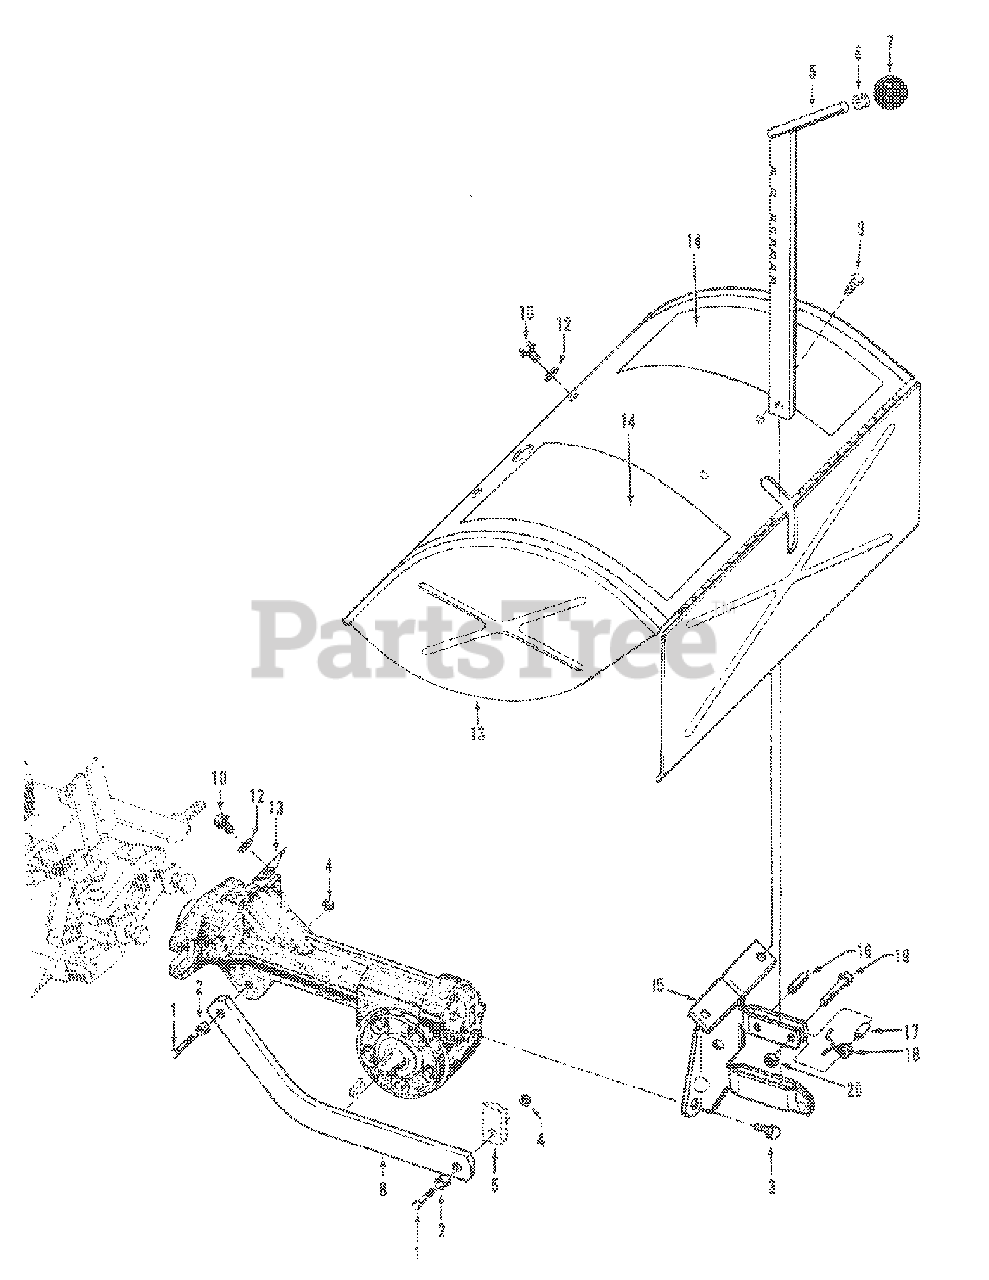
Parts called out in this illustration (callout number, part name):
1	Bolt-hex hd., 3/8-16 x 1-1/4"
2	Bushing-19/64" (.300" lg)
3	Bolt-flanged hex, 5/16-18 x 5/8"
4	Nut-hex, 3/8"-16
5	Bar-depth regulator
6	Ring-retaining
7	Knob-depth regulator
8	Bar-drag, depth
9	Screw-thread-forming, 1/4-20 x 1/2"
10	Bolt-flanged hex hd., 5?16-18 x 3/4"
12	Washer-flat, 5/16"
14	Decal-hood, operating instructions (LH)
14	Decal-hood, operating instructions (RH)
16	Pin-roll (spirol) 1/4" x 1"
17	Spacer, Split
19	Bolt-hex hd., 1/4- 20 x 1
20	Locknut-1/4"-20
